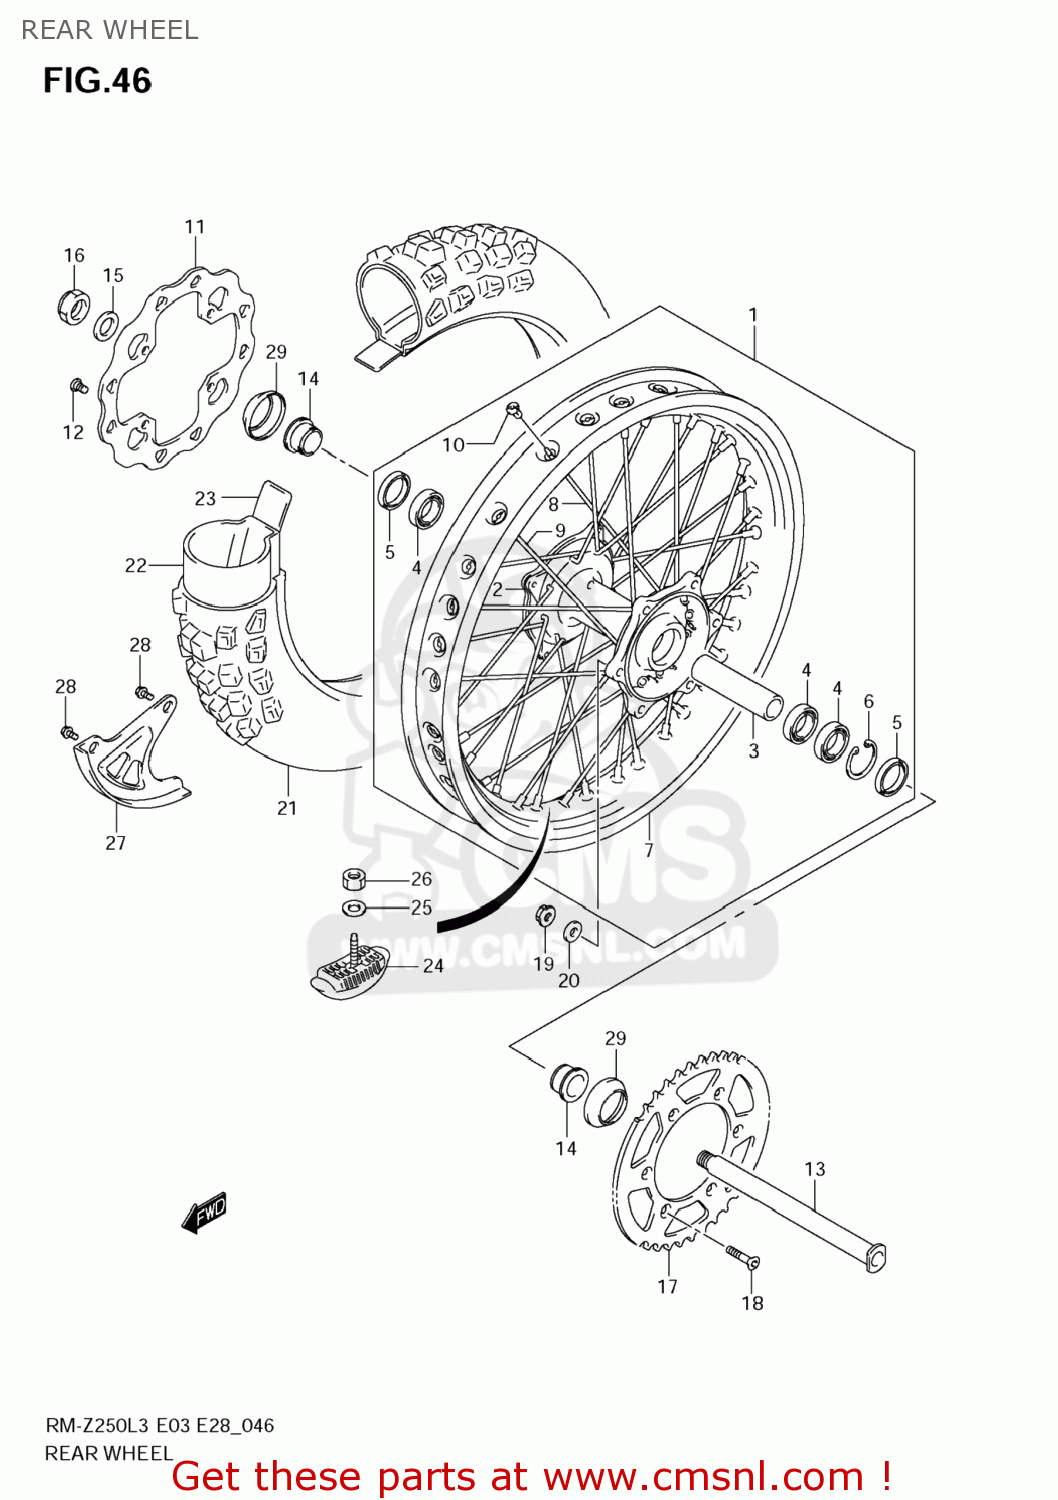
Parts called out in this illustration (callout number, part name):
1	WHEEL ASSY,RR
2	HUB,RR
3	SPACER,RR HUB BEARING
4	BEARING(25X42X9)
5	SEAL,OIL(32X43X7)
6	CIRCLIP
7	RIM,RR WHEEL(19X1.85 AL)(WHT)
8	SPOKE,RR WHEEL INNER
9	SPOKE,RR WHEEL OUTER
10	NIPPLE,RR WHEEL
11	DISC,RR BRAKE
12	SCREW(8X15)
13	AXLE,RR
14	SPACER,RR AXLE
15	WASHER(22X35X2)
16	NUT
17	SPROCKET,RR(NT:49)
18	BOLT(8X28)
19	NUT
20	WASHER(8.5X16X1.2)
21	TIRE,RR(100/90-19)
22	TUBE
23	PROTECTOR,WHL INR TUBE
24	STOPPER,BEAD(1.85)
25	WASHER
26	NUT
27	COVER,RR DISC
28	BOLT(6X12)
29	COVER,RR AXLE SPACER
